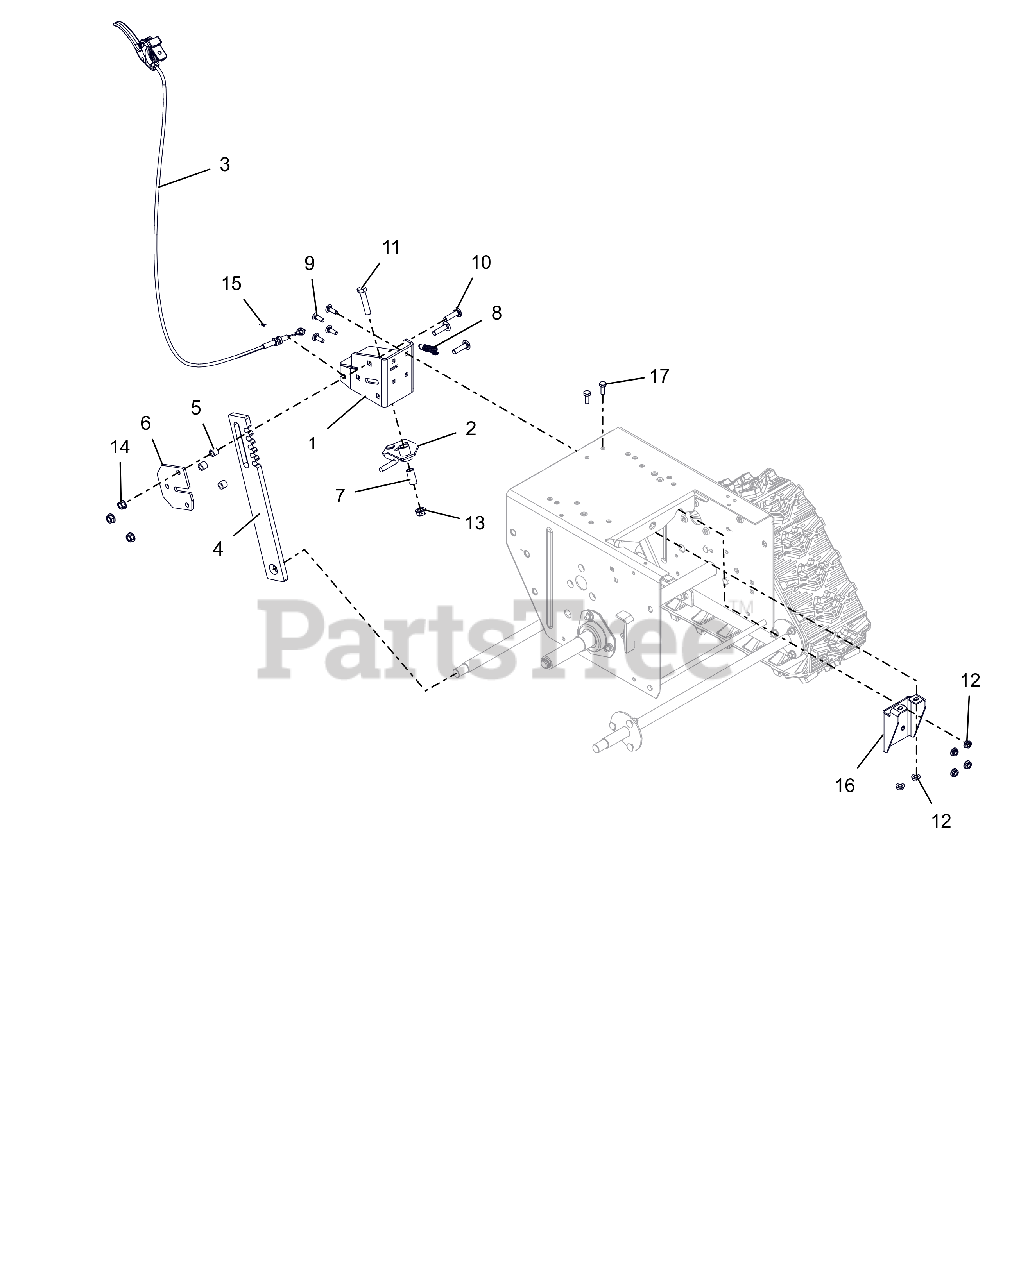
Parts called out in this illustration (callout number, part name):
1	BRACKET,HEIGHT ADJUSTER-PRO
2	LOCK,HEIGHT ADJUSTER TRIGGER
3	CABLE, TRACK REMOTE
4	STOP, HEIGHT ADJUSTER-PRO
5	SPACER .50 X .32 X .42
6	PLATE, HEIGHT ADJUSTER
7	BSHG-SLV .385X.500X1.045
8	SPRING-EXT .047 X .438 X 1.85
9	@BLT-RDHDSQNK .25-20X.75 G5YZ
10	@BLT-RHDSHSQNK.31-18X1.25 G5YZ
11	@BLT-HEX .38-16X1.75 GR5 YWZC
12	@NUT-LK-CTR-FLG .25-20 YWZC
13	NUT-LK-CTR-FLG .38-16 YWZC
14	@NUT-LK-TOP-FLG .31-18 YWZC
15	PIN-HAIR INT .06X.18X.77
16	BRACKET, REINFORCEMENT
17	@BLT-HEX .25-20X.75 GR5 YWZC
